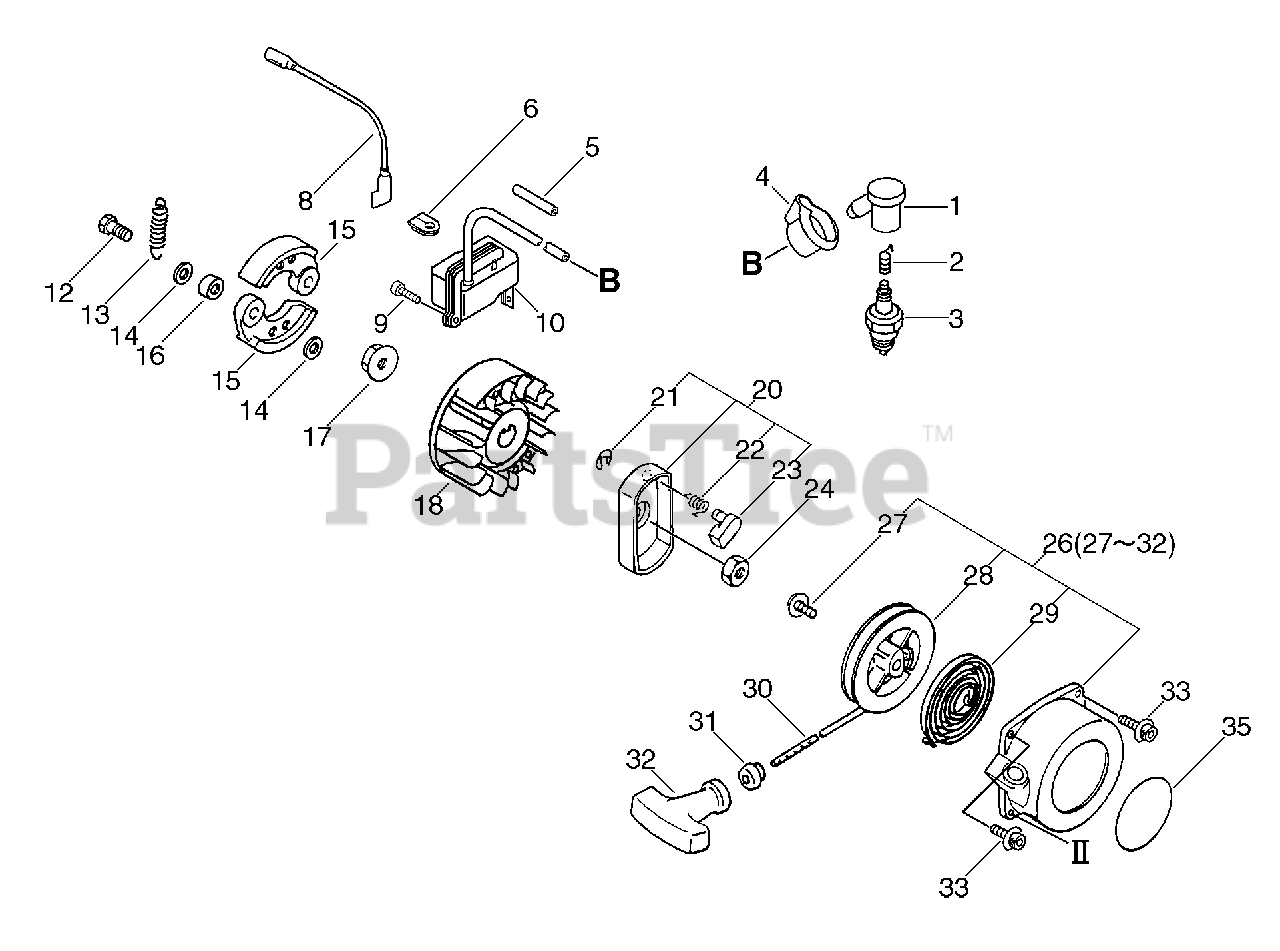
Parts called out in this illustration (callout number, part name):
1	CAP, SPARK PLUG
2	TERMINAL, SPARK PLUG CAP
3	SPARK PLUG -- RCJ-6Y
4	COVER, DUST
5	TUBE, INSULATOR
8	LEAD - GROUND
9	SCREW - 5X20
10	COIL, IGNITION
12	BOLT, CLUTCH
13	SPRING, CLUTCH
14	WASHER, CLUTCH
15	SHOE, CLUTCH
17	NUT - 10 -- FLANGE
18	FLYWHEEL
20	STARTER PAWL ASSY
21	RING, RETAINING - 4
22	SPRING, RETURN
23	PAWL, STARTER
26	STARTER ASSY
28	REEL, ROPE
29	SPRING, REWIND
30	ROPE, STARTER
31	GUIDE, ROPE
32	GRIP, STARTER
33	SCREW - 5X20
35	LABEL - ECHO
